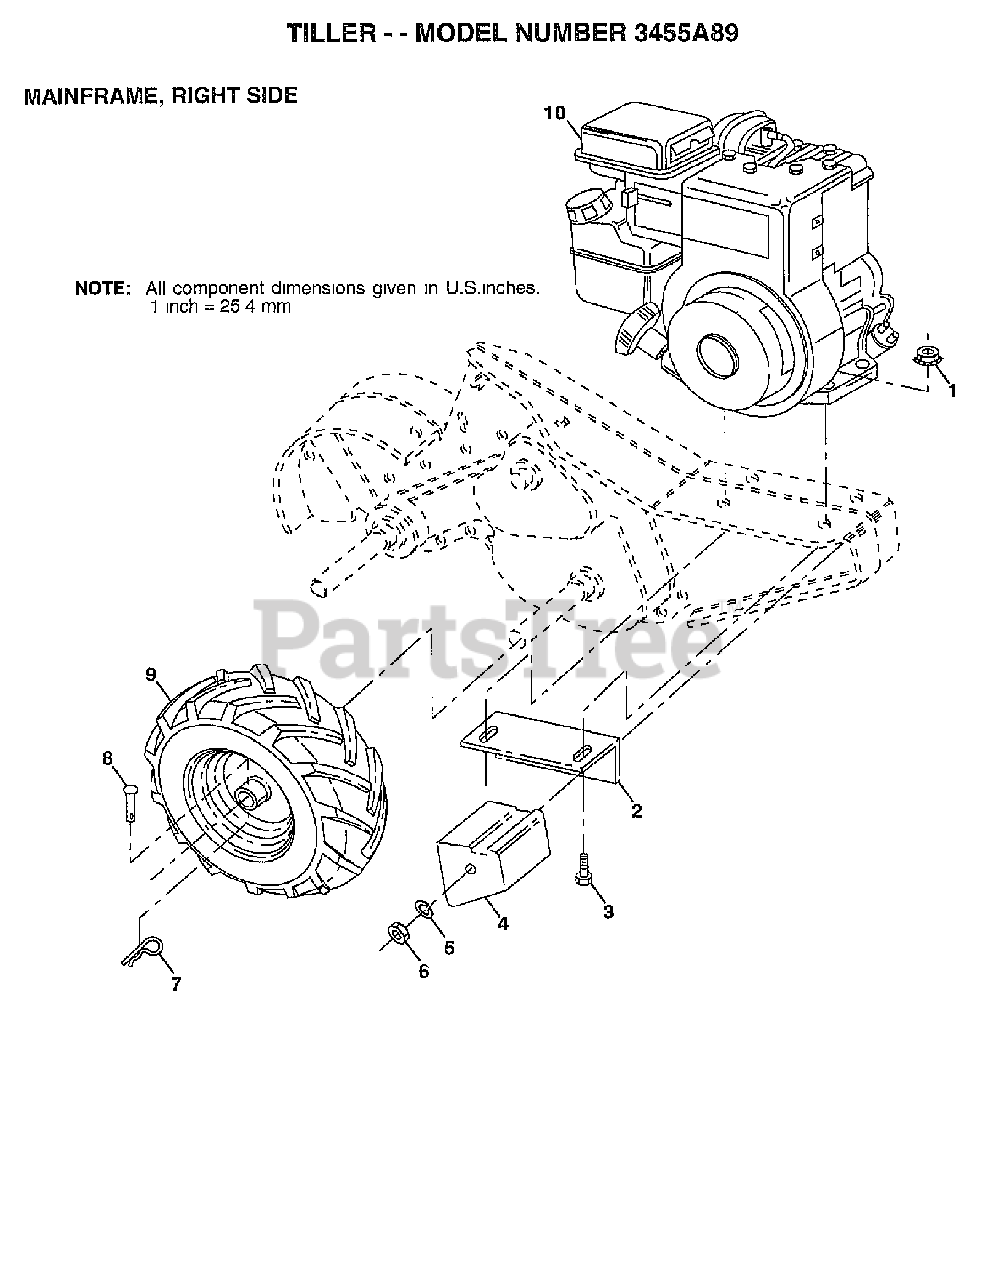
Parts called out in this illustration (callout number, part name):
2	BRACKET RH CRT
3	BOLT
4	COUNTERWEIGHT, RH
5	WASHER, LOCK 3/8
6	NUT.HEX.3/8-16UNC
8	RIVET CRT
9	TIRE.16X4-8.CHEVRON.TILLER
9	RIM
